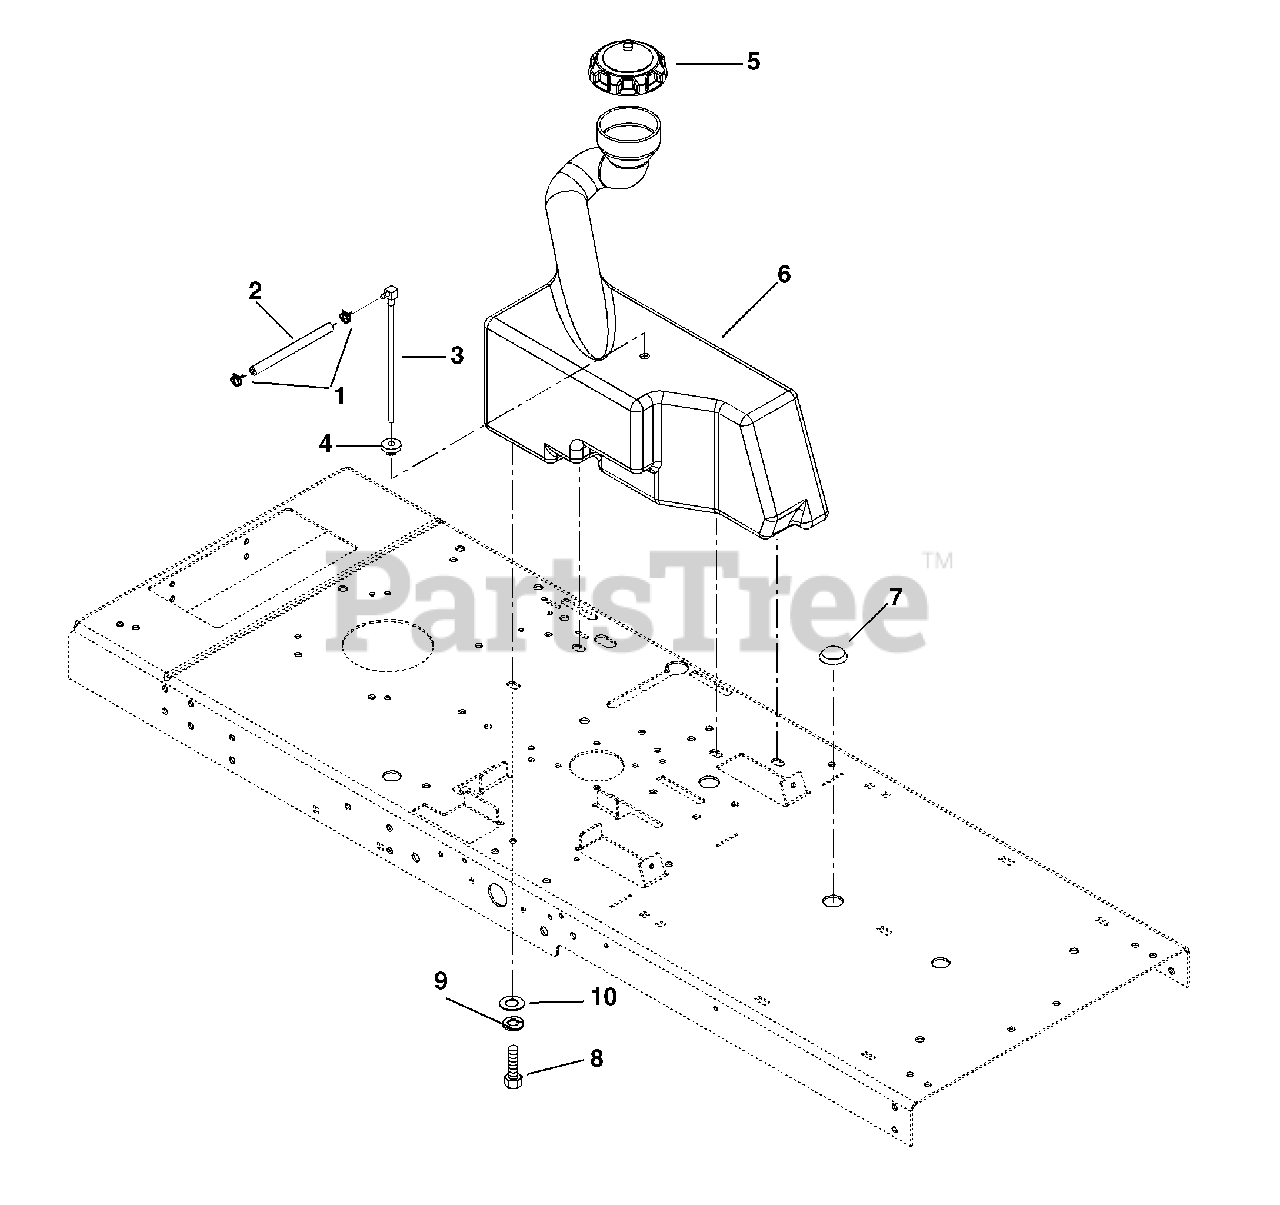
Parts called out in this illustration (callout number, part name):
1	CLAMP-HOSE WIRE .490/.510X.116
2	HOSE, FUEL .25 ID X 17.5 LG
3	FITTING, TANK
4	BSHG-FLG .375 X 1.062 X .625 R
5	CAP - FUEL
6	FUEL TANK
7	CAPLUG BUTTON PLUG
8	@BLT-HEX .31-18X.75 GR5 YWZC
9	@WSHR-LK .31X.078 REG YWZC
10	@WSHR-FL-STL.38X.875X.083 YWZC
